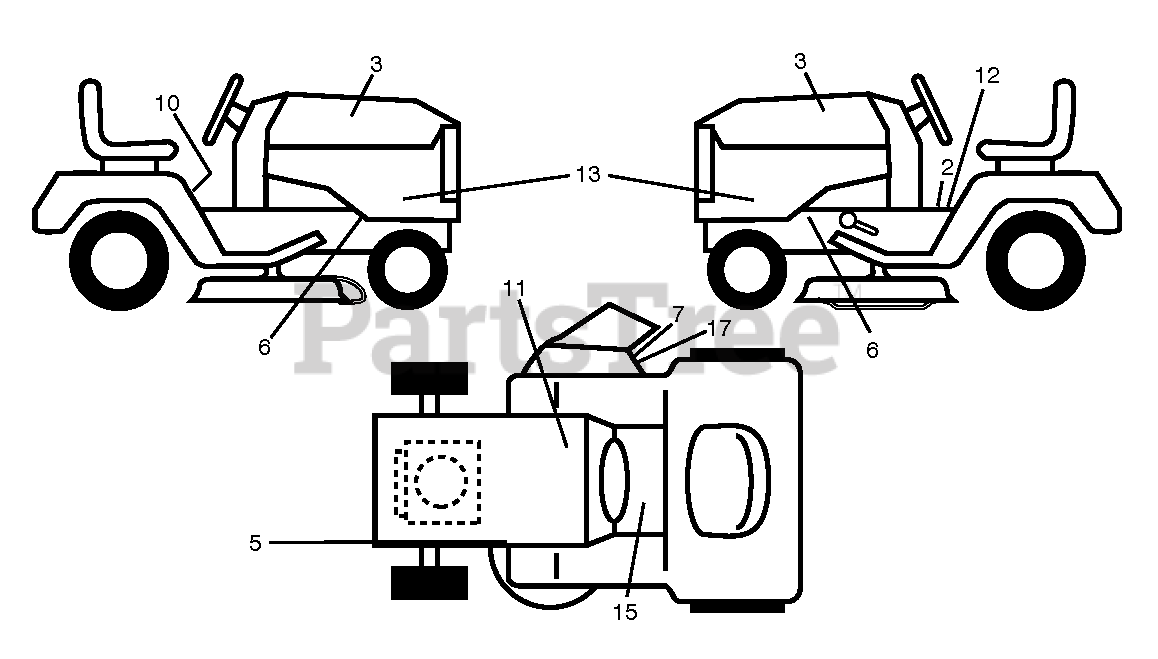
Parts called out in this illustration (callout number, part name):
1	DECAL.ENGINE.WARNING
2	DECAL.PARKING.BRAKE.SADDLE.LT
3	DECAL.BADGE.170MM.TEXTLOGO.
5	DECAL.V-BELT.SCH.42/46"MEC/ELE
6	DECAL.CHASSIS.HOT.MUFFLER
7	DECAL.CUTFINGER.CE.02
10	DECAL.READ.OWN.MAN.SYMBOL.LT
11	DECAL BTRY SYMBOLS
13	DECAL.SDPNL.LTH1842.KOH.HUSQ
15	DECAL.FNDR.SDLE.BRAKE.CLUTCH.6
17	DECAL.DFLCTR.WARNNG.CTFNGR.SYM
